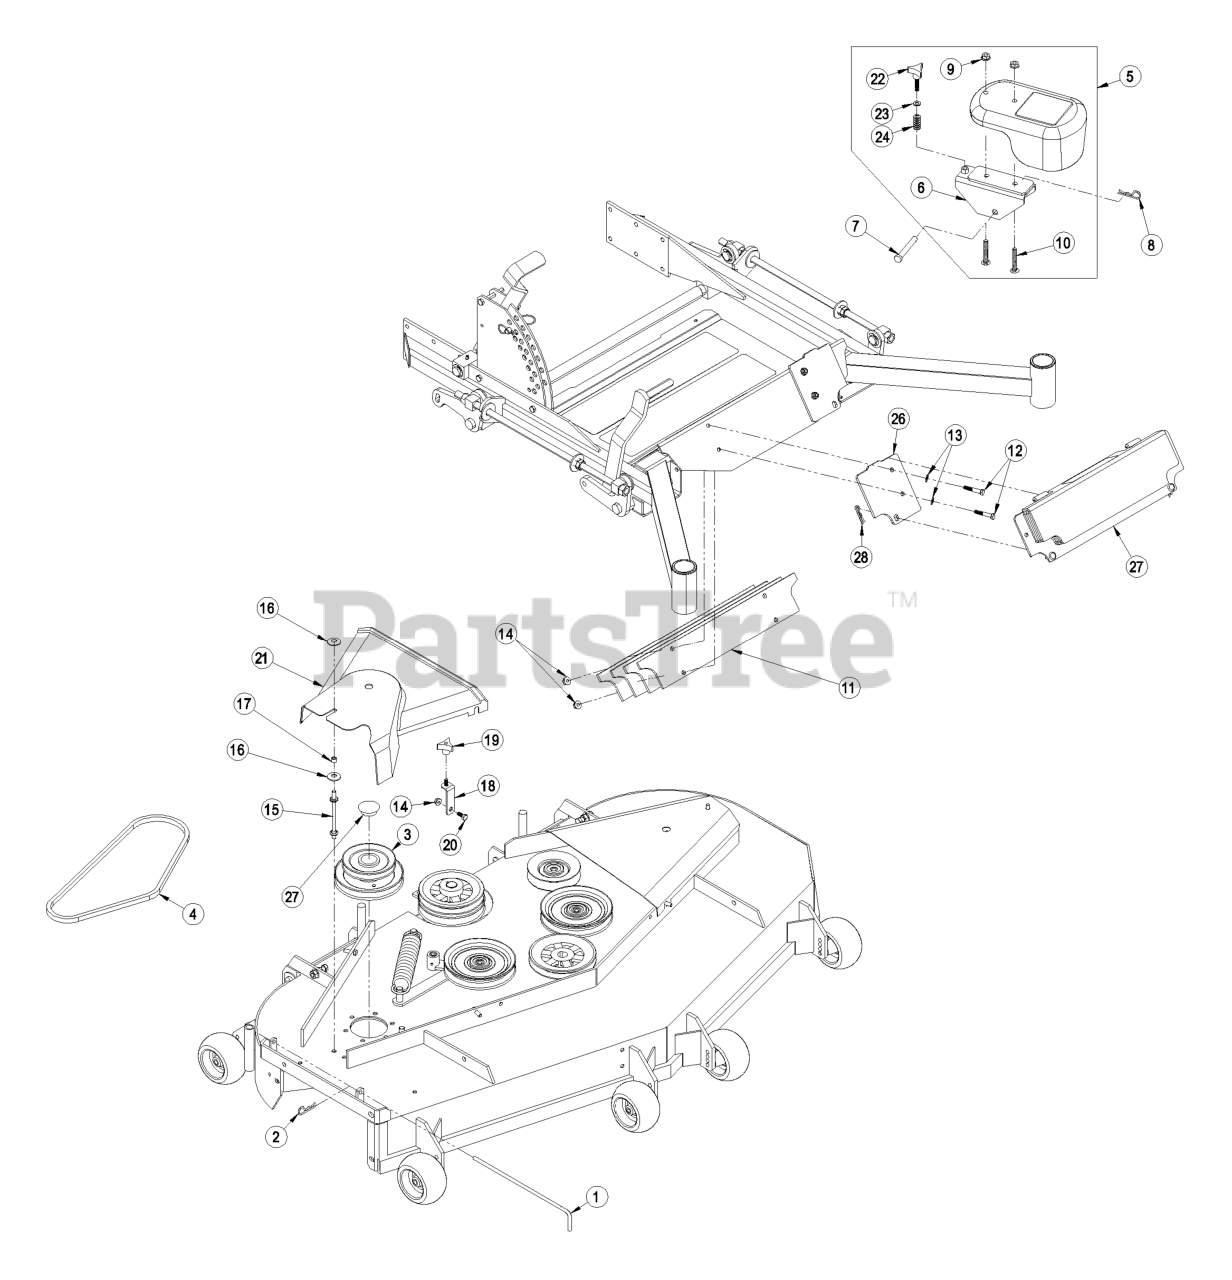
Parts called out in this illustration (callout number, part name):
1	PIN, CHUTE PIVOT
2	PIN-COTTER
3	JACKSHAFT, LZUV60
4	BELT, BLOWER DRIVE 60
5	ASM, WEIGHT 1.5" 70 POUND
6	WLD, BRACKET 2.0 ARM
7	PIN-CLEVIS
8	PIN-COTTER
9	NUT-HHF, WHIZ
10	BOLT, SQUARE HEAD YZ
12	SCREW-HH
13	WASHER-PLAIN
15	STUD,BELT SHIELD 4 INCH
16	WASHER-SPRING
18	Support, Belt Cover
19	Knob
21	COVER, BELT 60
23	WASHER-FLAT
25	PLUG, BLACK NYLON 1.75
26	PLATE, WEIGHT MOUNTING
27	ASM, WEIGHT PLATE WITH DE
28	PIN-HAIR
